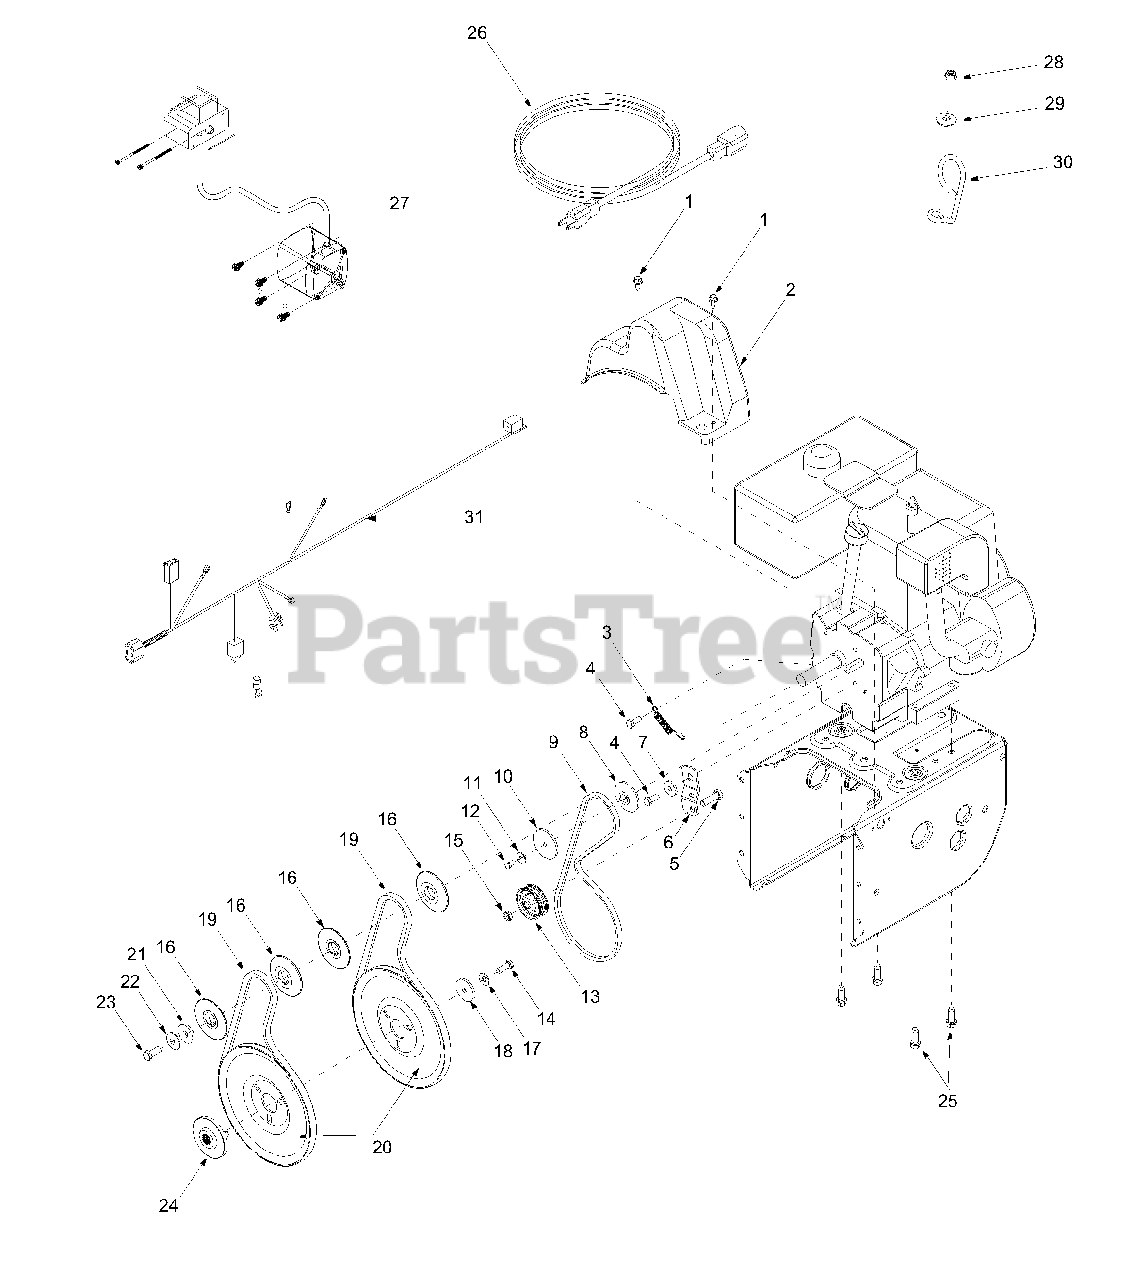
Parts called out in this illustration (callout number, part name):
1	Hex Washer Screw 1/4-20 x .625
2	Belt Cover
3	Extension Spring
4	Hex Screw 5/16-24 x .75
5	Hex Cap Screw 3/8-16 x 1.25
8	Pulley Half
9	V-Belt
10	Pulley Half
11	Bell Washer
12	Hex Cap Screw 1/4-28 x .50
13	Flat Idler
14	Lock Hex Cap Screw 5/16-24
15	Lock Jam Nut 3/8-16
16	Pulley Half
17	Bell Washer
18	Flat Washer
19	Belt
20	Auger Pulley
21	Flat Washer 3/8 x 1.25 OD
22	Bell Washer
23	Hex Cap Screw 3/8-24
24	Adapter Pulley
25	Hex Screw 3/8-16 x 1.0
26	Extension Cord
27	Electric Start Kit
28	Lock Nut, 1/4-20
29	Flat Washer, .28 x .74 x .063
30	Cable Guide
31	Upper Harness Assembly
